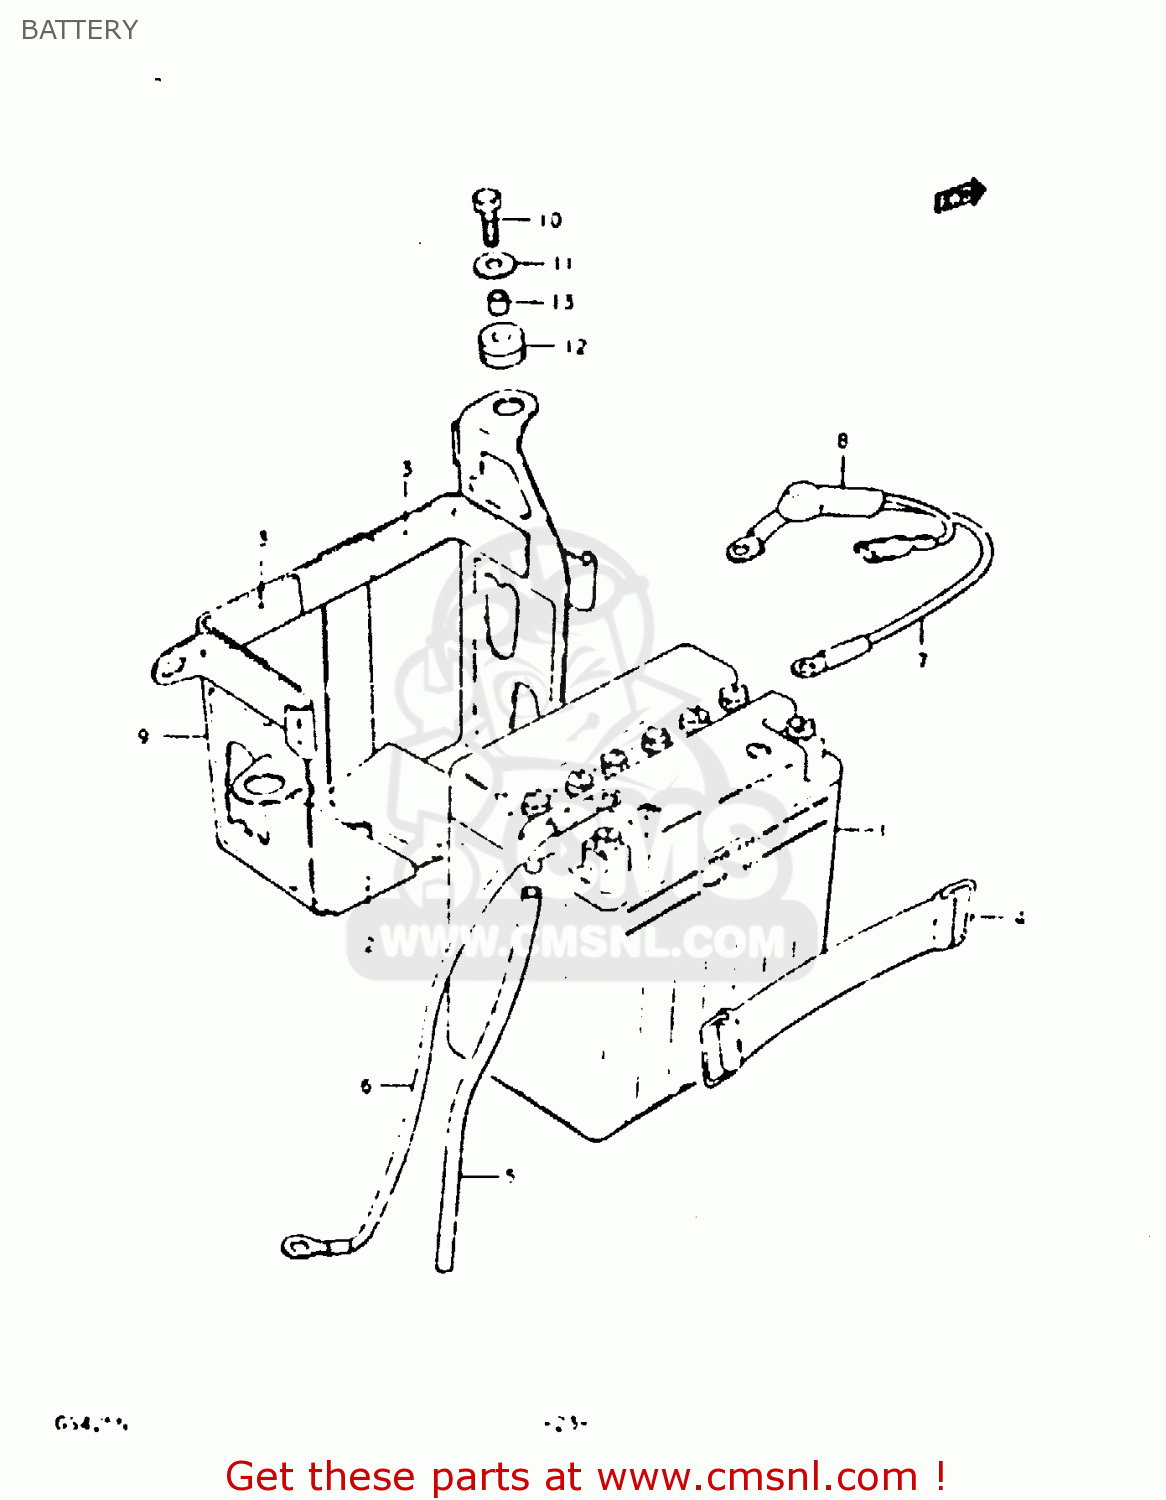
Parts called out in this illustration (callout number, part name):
1	BATTERY ASSY (12V)
2	CUSHION,BATTERY
3	PROTECTOR,20X9
4	BAND
5	HOSE,BATTERY EXHAUST
6	CORD,BATTERY MINUS
7	WIRE,BATTERY PLUS
8	CAP,TERMINAL
9	HOLDER,BATTERY
10	BOLT
11	WASHER
12	CUSHION
13	SPACER (6.1X9X9)
